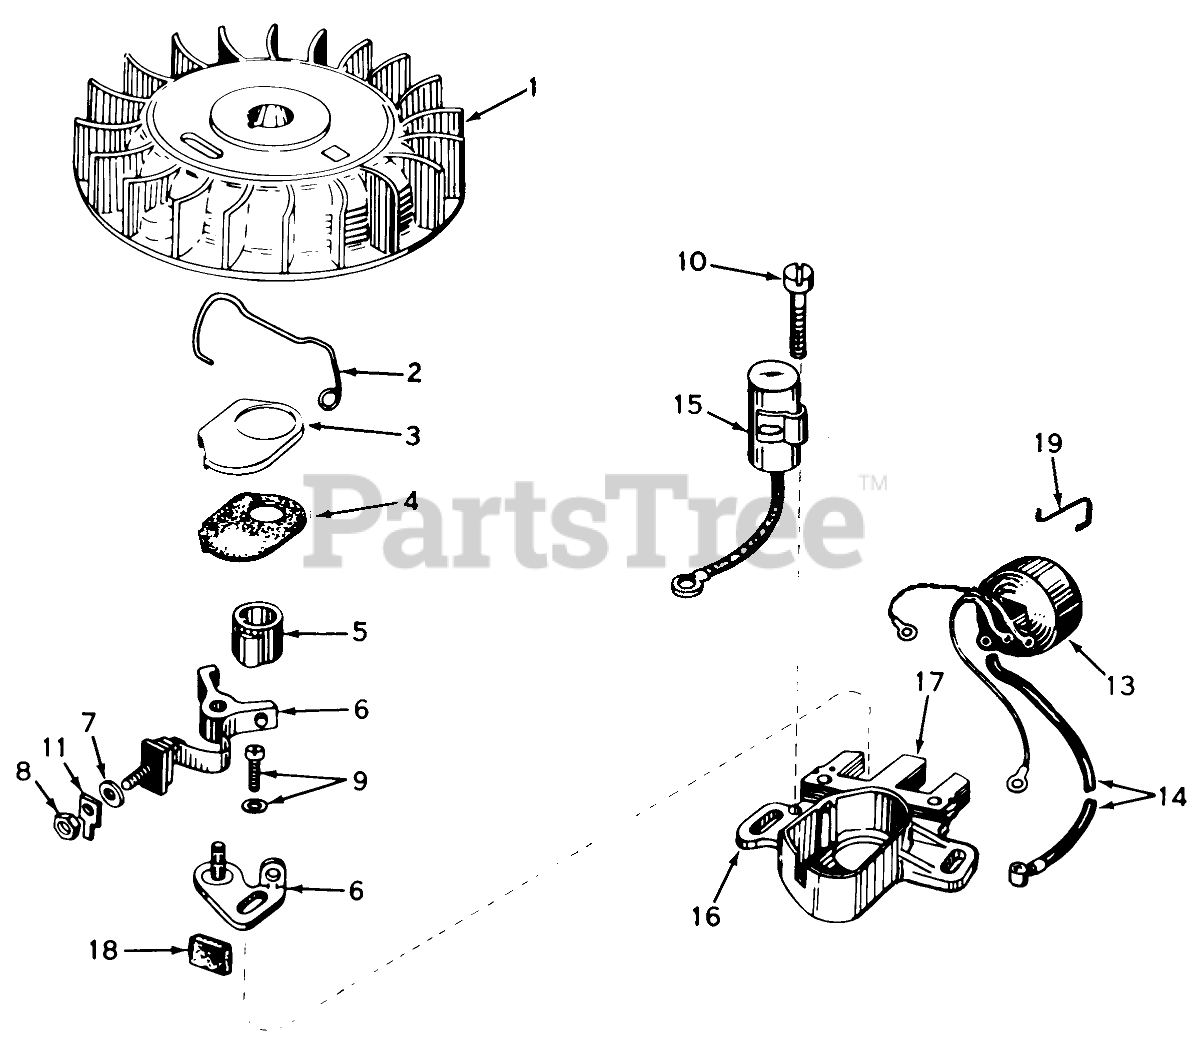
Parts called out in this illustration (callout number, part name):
1	Flywheel (Incl. Nos. 3 & 4)
2	Spring Breaker Box
3	Cover-Dust
4	Gasket, Dust Cover
5	Cam, Breaker
6	Breaker Assy.
7	Washer
8	DECAL
9	Breaker Screw
10	Condenser Screw
11	Terminal, Ground
13	Coil Assembly (Incl. No. 14)
14	Wire, Lead
15	Condenser
16	Core & Plate
17	Stator Assembly (Incl. Nos. 2, 3, 4, 6 thru 11, 13, 15, 16, 18 & 19)
18	Felt,Cam Wiper
19	Clip, Coil
